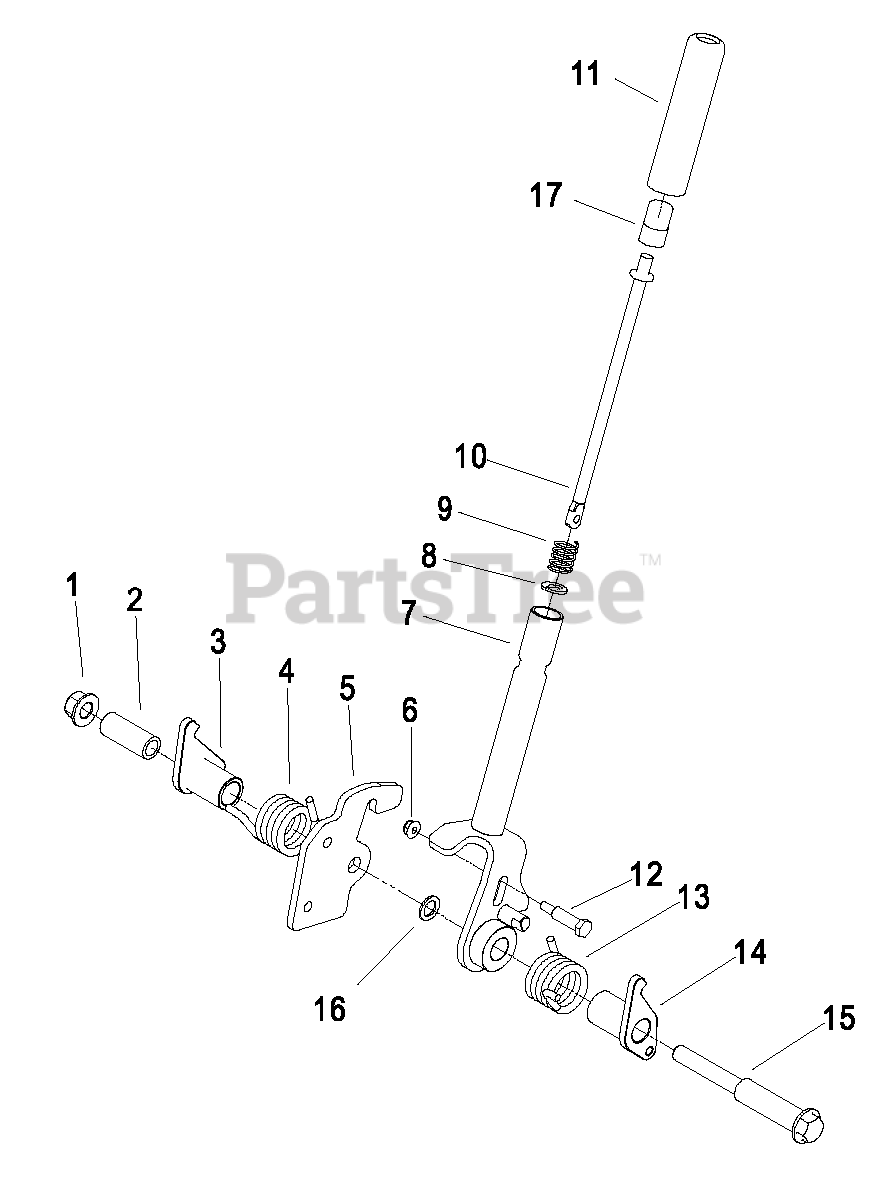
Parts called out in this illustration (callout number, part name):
1	Nut-Lock 1/2-13
3	ARM-BRAKE, LH
4	SPRING-TORSION, RH
5	PLATE-LATCH
8	WASHER-SPECIAL
9	SPRING-COMPRESSION
10	ROD-RELEASE, BRAKE
12	BOLT-SHOULDER
13	SPRING-TORSION, LH
14	ARM-BRAKE, RH
15	BOLT-SHOULDER
